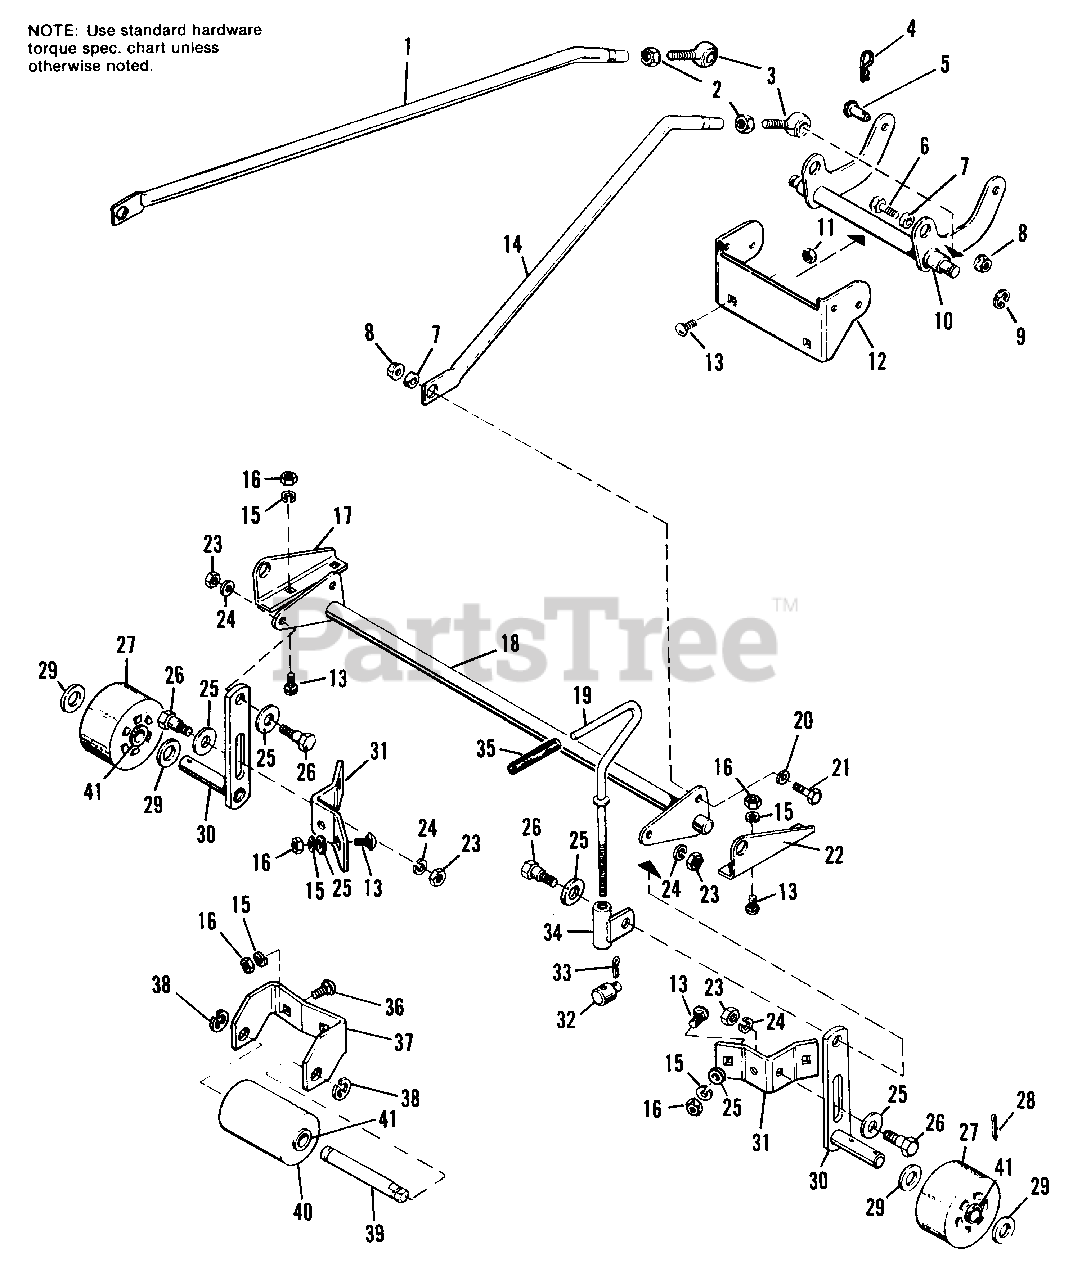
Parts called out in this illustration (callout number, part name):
1	ARM, Adjusting, L.H.
2	LOCKNUT, Jam, 1/2-20
4	CLIP, Hair Pin
6	BOLT, Shoulder
8	LOCKNUT, Hex, 3/8-16
9	RING, Retaining
10	ARM ASSY., Link
11	NUT, Hex, Flange, 5/16-18
12	BRACKET, Front, Mower
13	BOLT, Carriage, 5/16-18 x 5/8
14	ARM, Adjusting, R.H.
15	LOCKWASHER, 5/16 (Qty. 10 used on 991020)
16	NUT, Hex, Full, 5/16-18 (Qty. 10 used on 991020)
17	BRACKET, Pivot, L.H.
18	ARM ASSY.
20	WASHER, Plain, 3/8
21	CAPSCREW, Hex Hd., 3/8-16 x 1
22	BRACKET, Pivot, R.H.
23	NUT, Hex, Full, 3/8-16
24	LOCKWASHER, 3/8
25	WASHER, Plain, 7/16
26	BOLT, Shoulder, 3/8-16 X 1.34
27	ROLLER ASSY.
28	PIN, Cotter, 3/16 x 1
29	WASHER, Plain, 5/8
30	SUPPORT ASSY., Roller
31	BRACKET, Support, Roller
33	PIN, Cotter, 3/32 x 1
34	GUIDE ASSY., Rod
36	BOLT, Carriage, 5/16-18 x 3/4
37	BRACKET, Center, Roller
38	RING, Retaining
39	SHAFT, Roller, Center
40	ROLLER ASSY
